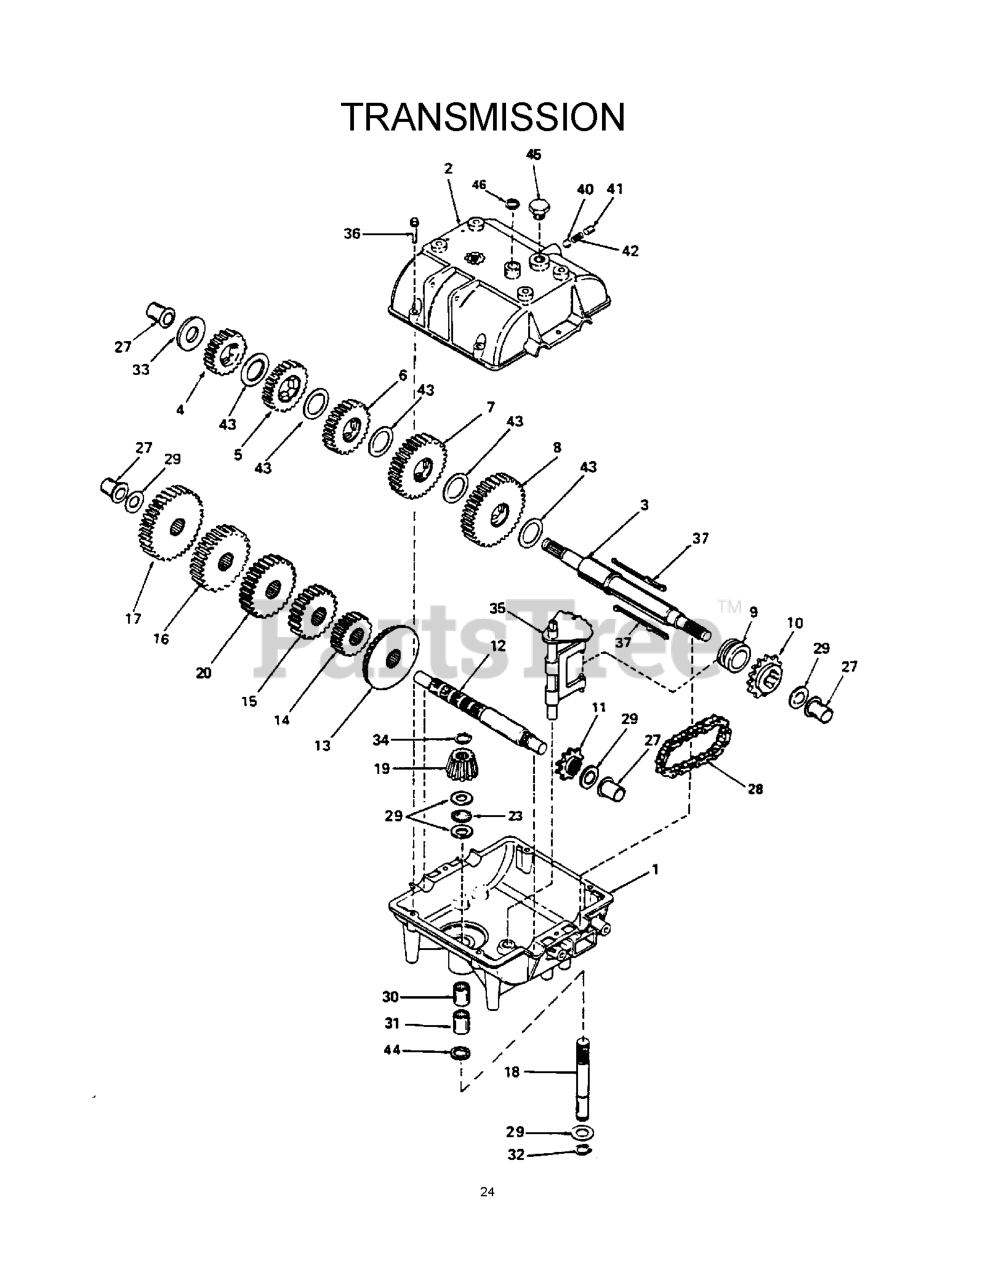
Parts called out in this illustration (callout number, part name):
1	TRANSMISSION CASE
2	TRANSMISSION COVER
3	OUTPUT & BRAKE SHAFT
4	SPUR GEAR (27 TEETH)
5	SPUR GEAR (30 TEETH)
6	SPUR GEAR (32 TEETH)
7	SPUR GEAR (35 TEETH)
8	SPUR GEAR (37 TEETH)
9	SHIFT COLLAR
10	SPROCKET (18 TEETH)
11	SPROCKET (9 TEETH)
12	COUNTERSHAFT
13	GEAR, BEVEL (42 TEETH)
14	SPUR GEAR (12 TEETH)
15	SPUR GEAR (15 TEETH)
16	SPUR GEAR (20 TEETH)
17	SPUR GEAR (23 TEETH)
18	INPUT SHAFT
19	INPUT BEVEL PINION
20	SPUR GEAR (18 TEETH)
23	THRUST BEARING
27	BUSHING, FLANGED
28	CHAIN, ROLLER #41 24 LINK
29	THRUST WASHER
30	NEEDLE BEARING
31	NEEDLE BEARING
32	RETAINING RING
33	WASHER, THRUST
34	RETAINING RING
35	SHIFT ROD & FORK
36	W-FLANGED HEX HD THREADFOR
40	STEEL BALL, 5/16"
41	SET SCREW, 3/8-16 X 3/8"
43	THRUST WASHER
44	"O" RING
45	THREADED PLUG
46	SQUARE CUT SEAL
47	COMPLETE TRANSMISSION
